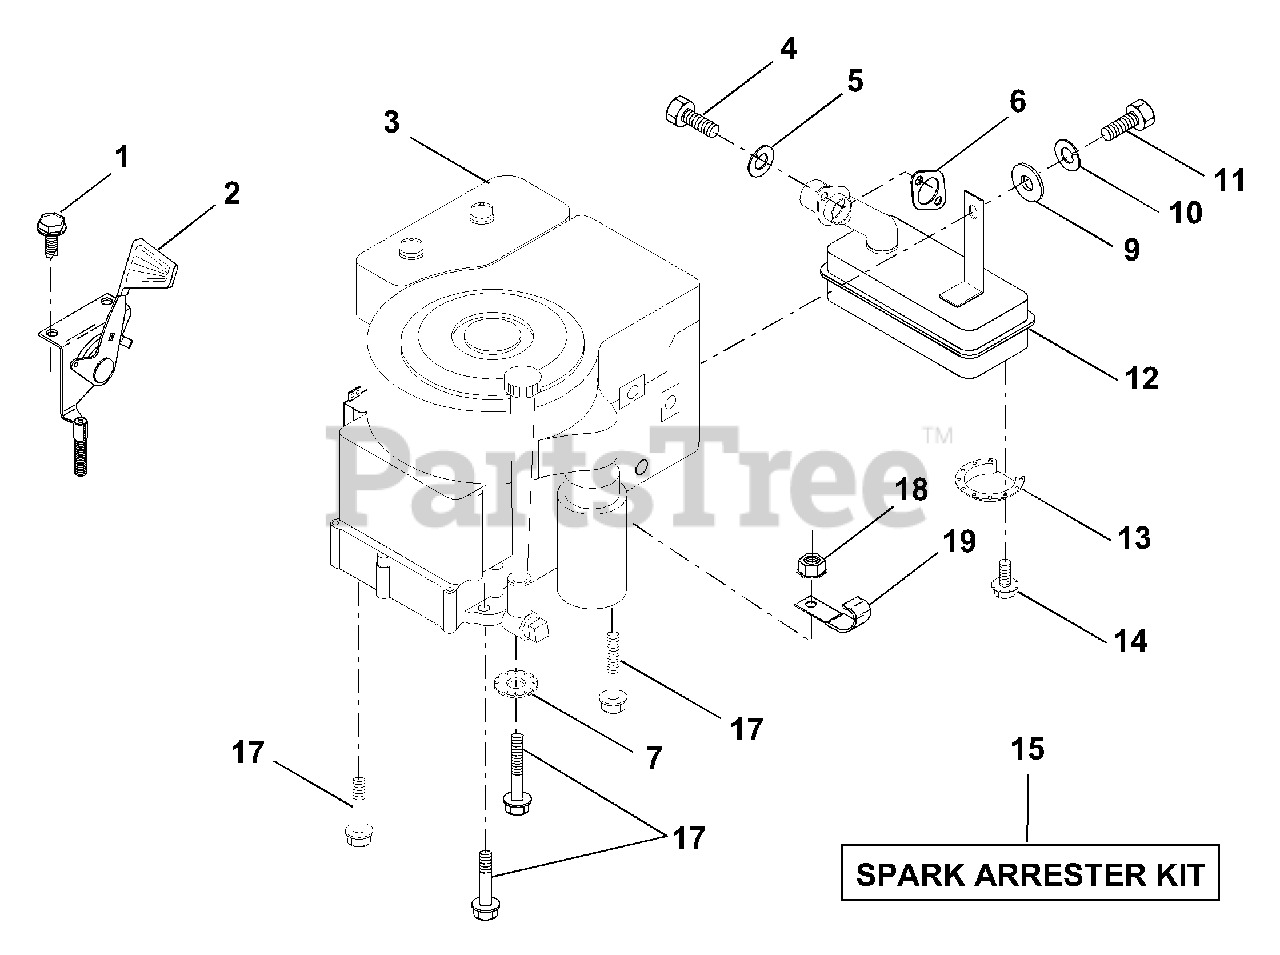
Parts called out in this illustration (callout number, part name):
1	Screw, Hex Thd. Cut 1/4-20 x 1/2
2	Control, Throttle
4	Screw, Hex, Cap 5/16-18 x 3/4
5	Washer, Lock Heavy Helical Spring 5/16
6	Gasket, Exhaust
7	Washer Lock Ext. Tooth 3/8
9	Washer 5/16 x 3/4 x 16
10	Washer, Lock Hvy Hlcl Spring 1/4
11	Bolt, Hex Fin.
13	Deflector, Muffler
14	Screw, Spiderloc
15	Arrester, Spark
17	Screw, Hex Washer Head, Thdrol. 3/8-16 x 1-1/2
18	Nut, Keps 3/8-16
19	Clip, Line Fuel
